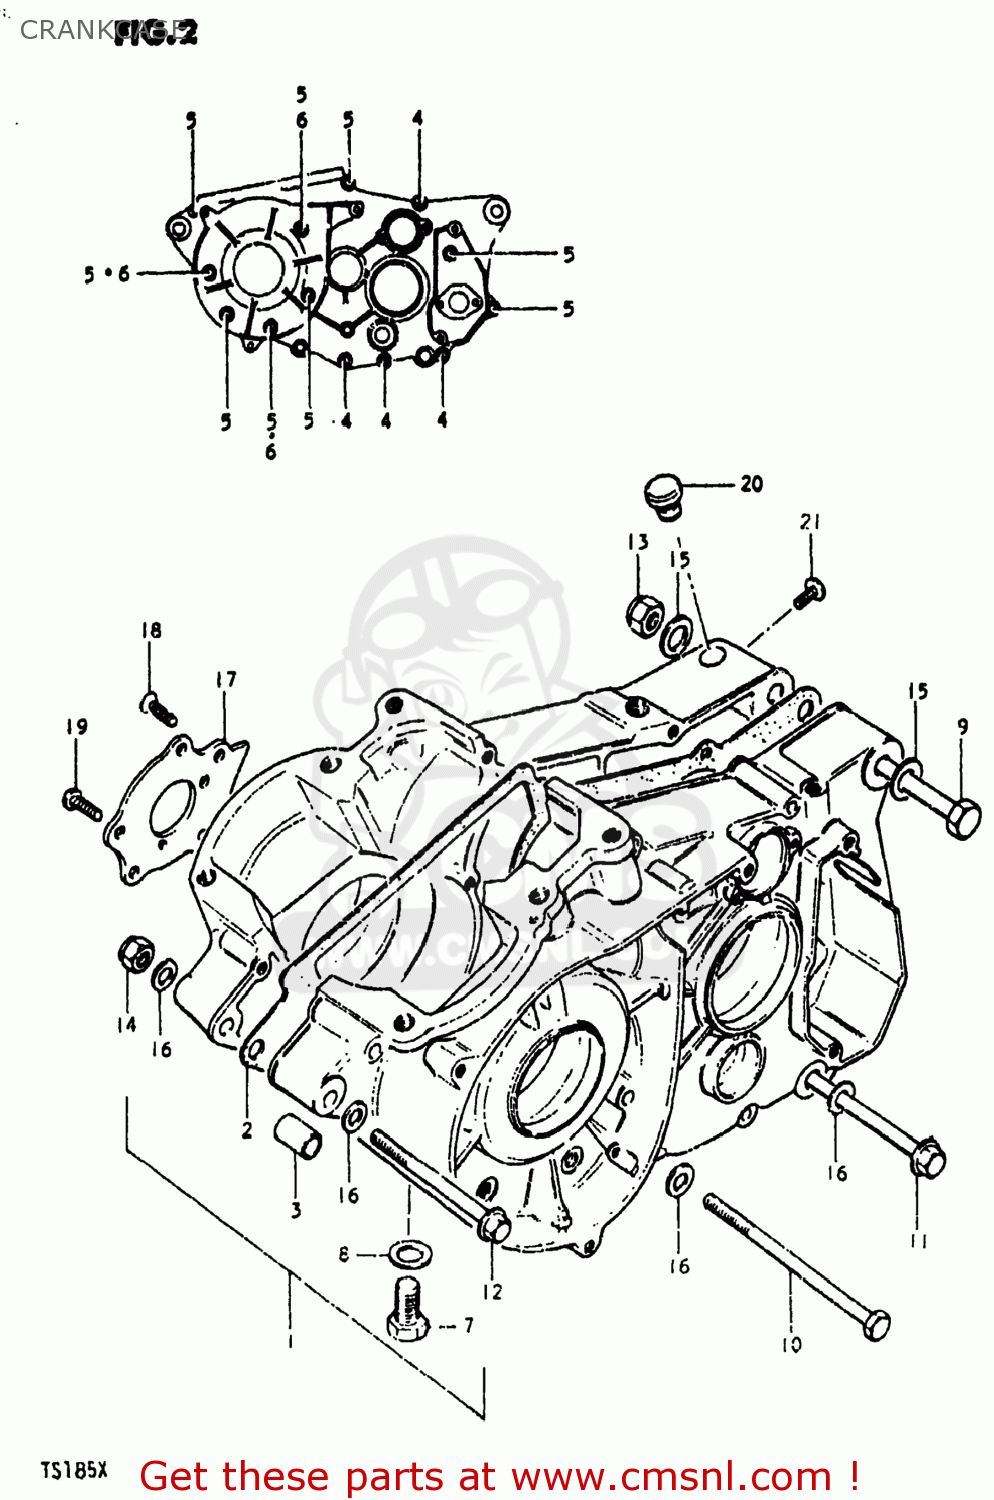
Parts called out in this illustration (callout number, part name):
1	CRANKCASE SET
2	GASKET,CRANKCASE (MCA)
3	PIN
4	SCREW 6X65
5	SCREW (6X45)
6	WASHER 6MM
7	PLUG
8	GASKET(14X19.2X2) (NAS)
9	BOLT
10	BOLT(8X145)
11	BOLT
12	BOLT
13	NUT
14	NUT
15	WASHER
16	WASHER
17	PLATE,OIL RESERVOIR
18	SCREW
19	SCREW
20	Plug
21	SCREW,6X6
